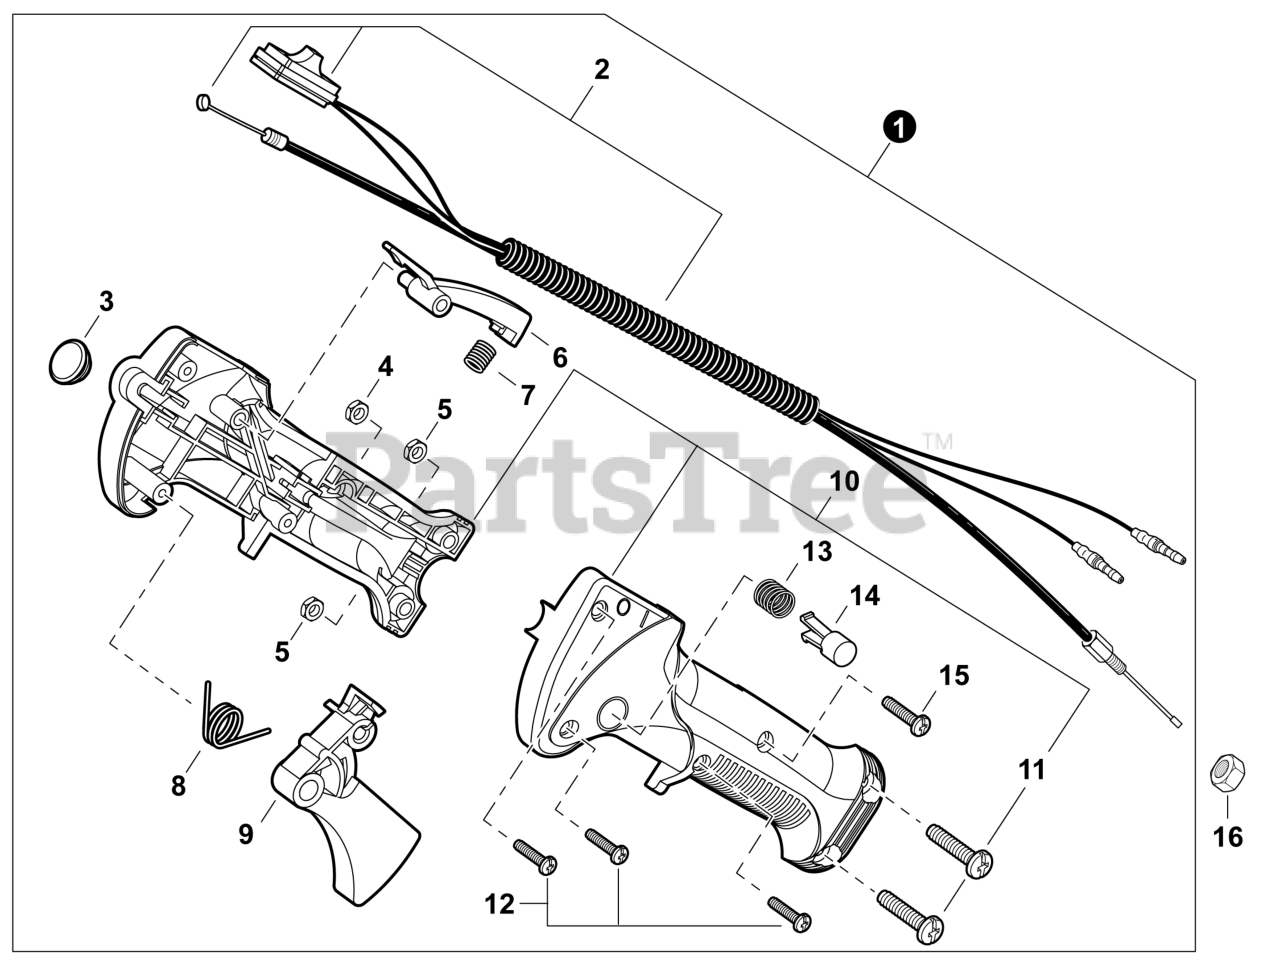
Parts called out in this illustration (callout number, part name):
1	THROTTLE CONTROL ASSY
2	CABLE ASSY, CONTROL
3	PLUG, RUBBER
6	LOCKOUT, THROTTLE
7	SPRING, COMPRESSION
8	SPRING, TORSION
9	TRIGGER, THROTTLE
10	HANDLE KIT, CONTROL
11	SCREW M5×22
12	SCREW, TAPPING 4×16
13	SPRING, COMPRESSION
14	BUTTON, THROTTLE LOCK
15	SCREW M4×23
